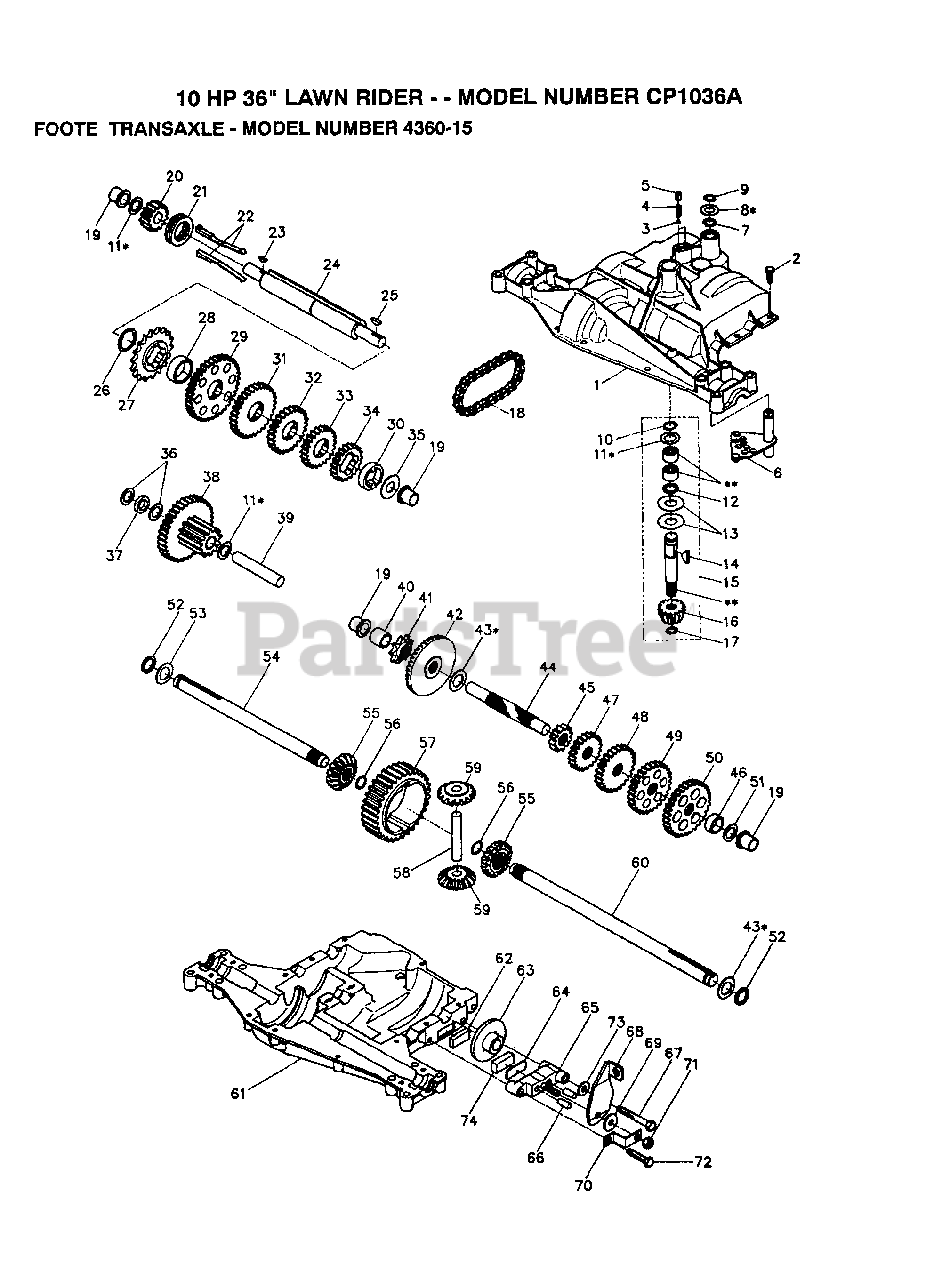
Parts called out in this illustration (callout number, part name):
1	HOUSING UPPER
3	BALL DETENT
4	SPRING, DETENT
5	SCREW, SET
6	ASSY SHIFTER
8	WASHER PLAIN
9	RING RETAINING
10	RING RETAINING
11	WASHER PLAIN
13	WASHER, PLAIN .632 X 1.38 X .046
14	KEY WOODRUFF #9
15	ASSY KIT INPUT SHAFT
16	PINION, BEVEL, 14 TEETH
17	RING, RETAINING
18	CHAIN, 24 PITCHES
19	BEARING, FLANGE
20	GEAR SPUR, 14 TEETH
21	COLLAR CLUTCH
22	KEY CLUTCH
23	KEY WOODRUFF #3
24	SHAFT INTERMEDIATE
25	KEY, WOODRUFF, #61
26	RING, RETAINING
27	SPROCKET, 18 TEETH
29	GEAR, SPUR, 37 TEETH
31	GEAR, SPUR, 30 TEETH
32	GEAR, SPUR, 25 TEETH
33	PUCK, FRICTION
35	WASHER, PLAIN .640 X 1.37 X .061
36	WASHER, PLAIN .632 X 1.00 X .026
37	SPACER .630 X 1.00 X .169
38	ASSY GEAR COMB 12&35 TEETH
39	SHAFT IDLER
40	SPACER .635 X .875 X .755
41	SPROCKET, 9 TEETH
42	GEAR, BEVEL, 42 TEETH
43	WASHER PLAIN
44	SHAFT, DRIVE
45	GEAR, SPUR, 12 TEETH
46	SPACER .781 X 1.00 X .750
47	GEAR, SPUR, 20 TEETH
48	GEAR, SPUR, 25 TEETH
49	WASHER PLAIN
50	GEAR, SPUR, 31 TEETH
51	WASHER, PLAIN .632 X 1.00 X .060
53	WASHER PLAIN
54	AXLE LEFT HAND
55	GEAR, MITER, 15 TEETH
56	RING, RETAINING
57	GEAR, SPUR, 32 TEETH
58	SHAFT, CROSS
59	GEAR, MITER, 15 TEETH
60	AXLE RIGHT HAND
61	HOUSING LOWER
62	PUCK, FRICTION
63	DISC, BRAKE
65	JAW, BRAKE
66	PIN, DOWEL
67	SCREW TAPPING
68	LEVER, ACTUATING
69	WASHER, PLAIN .321 X 1.00 X .055
70	BRACKET, ANTI-ROTATION
71	LOCKNUT 5/16-24
72	SCREW TAPPING
